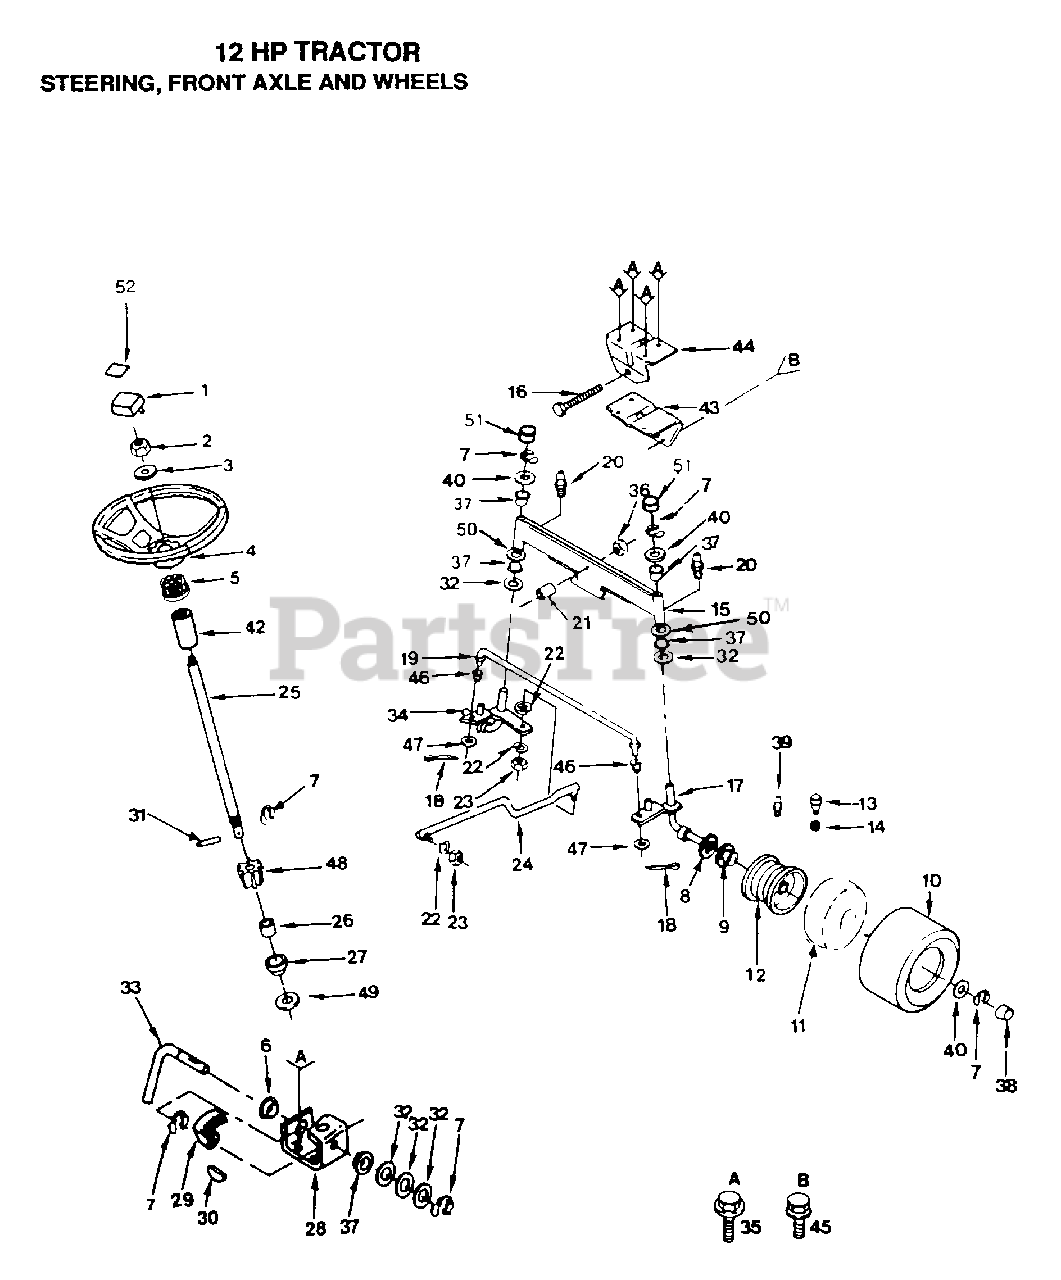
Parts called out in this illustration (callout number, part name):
3	WASHER
6	NYLINER T
7	RING
8	WASHER
9	"FLANGE, BEARING"
11	TUBE.5.3/4.5/6
13	VALVE STEM LT
14	VALVE CAP
16	BOLT LT
18	COTTER PIN
20	ZERK M
21	BEARING
22	LOCKWASHER
24	LINK-DRAG LT
26	SHAFT SPACER LT
27	BUSHING
29	GEAR.SECTOR.HYT
30	KEY-WOODRUFF LT
32	WASHER .T
33	ROD STEERING T
34	SPINDLE-LH LT
35	SCREW
36	"NUT-LOC,FLANGE LT"
37	COL. SRTG. BEAR.
38	HUB CAP
39	FITTING LT
40	WASHER
43	SUPPORT.SADDLE.FT
44	SUPPORT-SADDL T
45	SCREW LT
47	WASHER
48	GEAR PINION T
50	WASHER
51	CAP
52	DECAL, STEERING
